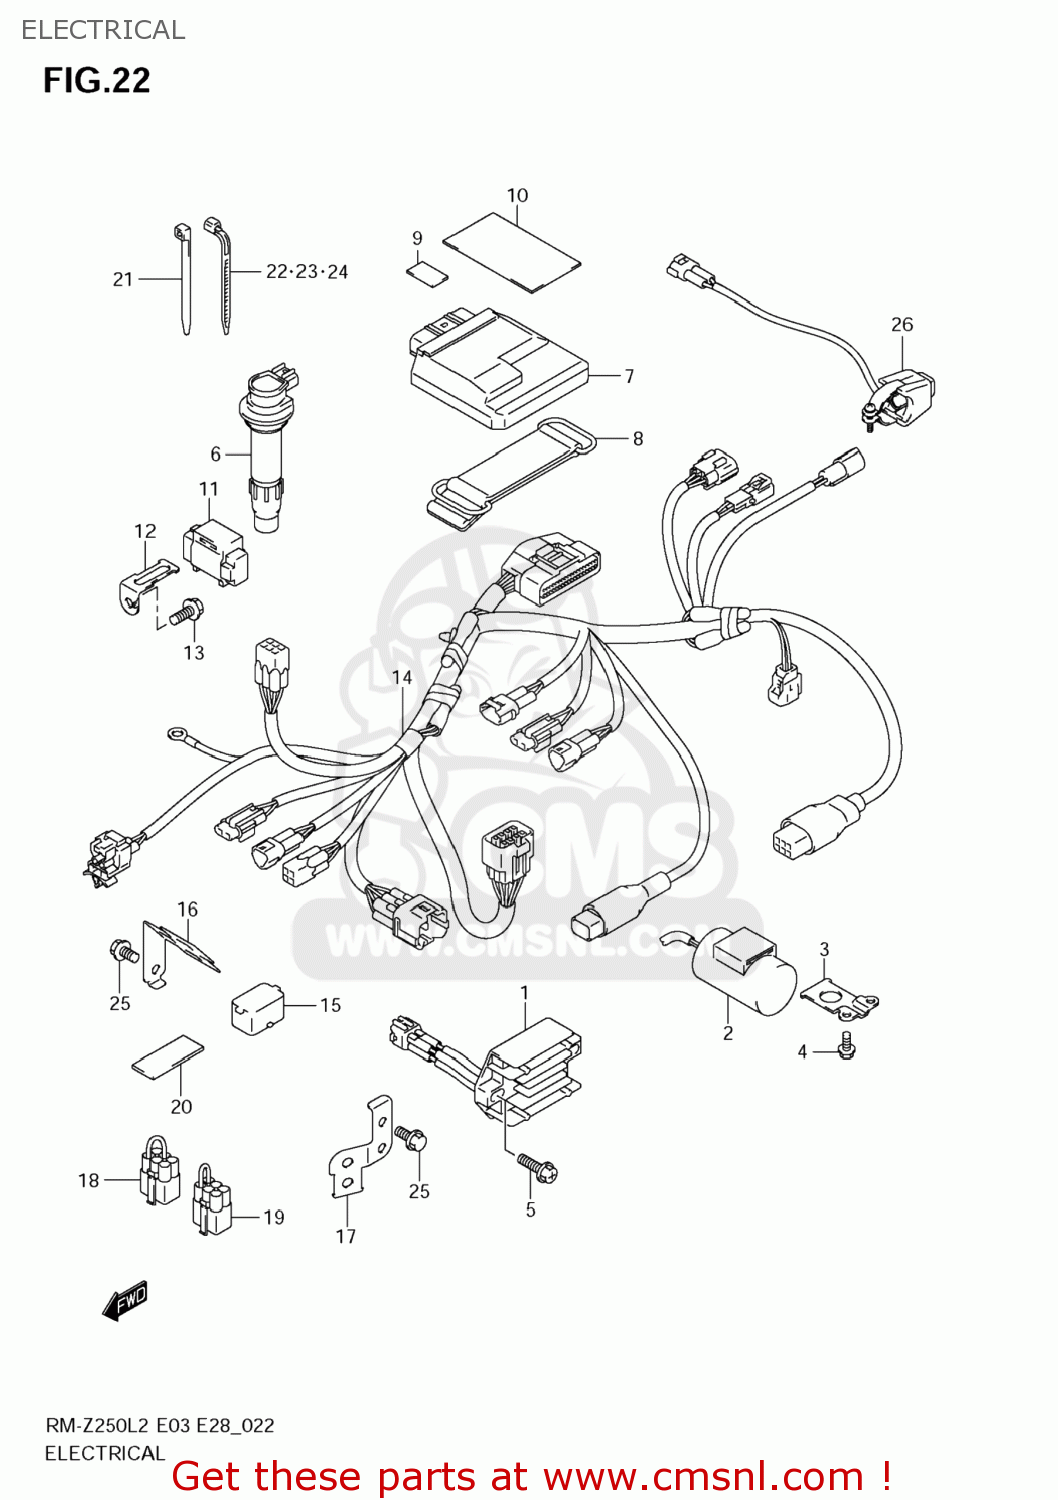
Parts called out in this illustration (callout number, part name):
1	RECTIFIER ASSY
2	CONDENSER ASSY
3	BRACKET,CONDENSER
4	BOLT(6X10)
5	SCREW
6	COIL ASSY,IGNITION
7	CONTROL UNIT,FI
8	BAND,CDI UNIT(L:80)
9	CUSHION(30X50X3)
10	CUSHION(30X50X3)
11	SENSOR ASSY,FUEL CUT
12	BRACKET,FUEL CUT SENSOR
13	SCREW
14	HARNESS,WIRING
15	CAP,TS
16	BRACKET,COUPLER
17	BRACKET,COUPLER
18	WIRE,SHORT
19	WIRE,SHORT
20	PROTECTOR,WIRING HARNESS
21	CLAMP(L:95)
22	CLAMP(L:95)
23	CLAMP(L:125)
24	CLAMP(L:165)
25	BOLT
26	SWITCH ASSY,ENGINE STOP
